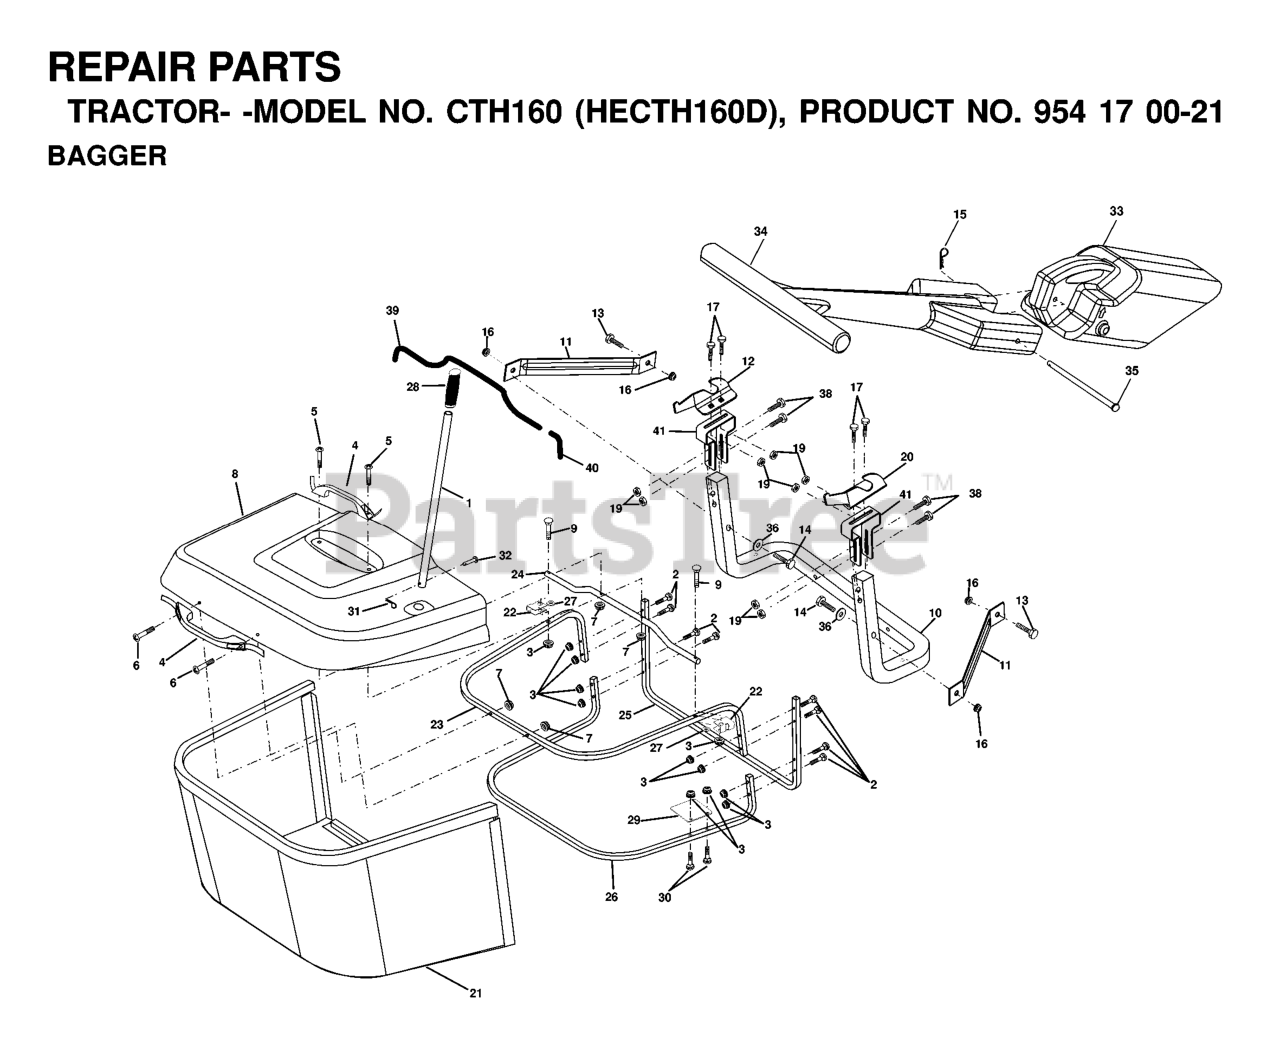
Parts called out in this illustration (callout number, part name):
1	TUBE HANDLE
2	Bolt Carriage 1/4-20 x 2.0 Gr.5
3	NUT T
4	HANDLE.BAGGER.W/LVRS.BLK.CRD
5	SCREW.PAN.HEAD
6	REPL BY 532 75 00-29
8	COVER
9	Bolt Carriage 1/4-20 x 2.25d x Gr.5
10	TUBE
11	BRACKET.SUPPORT.UPPER.BAG.CRD
14	Bolt Hex 3/8-16 x 2-1/2 Gr. 5
15	RETAINER-SPRNG RB
16	NUT LOCK FLG 3/8-16 UNC
17	RP BOLT 5/16-18 X3/4 ZN/YEL GR
18	WASHER M
19	NUT.71038.31-18.HEX.NYLOCK
20	BRACKET
21	BAG
22	BRKT.SIDE.BAG.CRD
23	TUBE.UPPER.BAG.CRD
24	TUBE.PIVOT.BAG.CRD.BLACK
26	TUBE.LOWER.BAG.CRD
28	GRIP.HANDLE.BLACK
30	Bolt Carriage 1/4-20 x 1 Gr.5
31	RETAINER M
32	RIVET,DRILLED
33	MULCH PLUG, CTH150
34	HANDLE.MULCHER.92.CRD (2 2)
36	WASHER
38	BOLT.5/16-18X2.5
39	TRIM
40	TRIM
41	BRKT.VERT.ADJ.BAGGER.CRD
